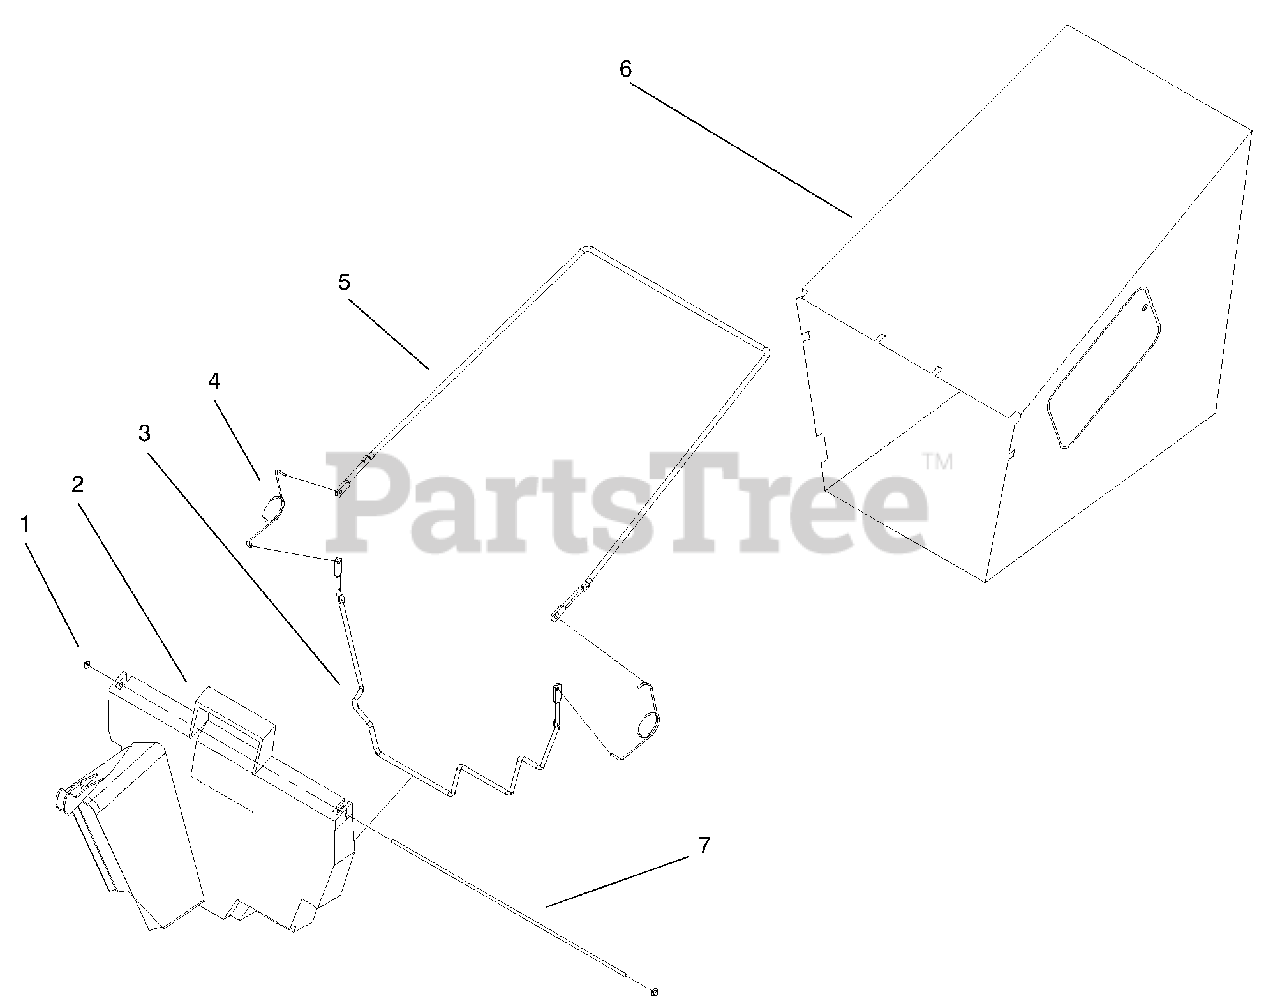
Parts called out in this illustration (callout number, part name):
2	Door-Bag
3	Frame-Lower Bag
5	Frame-Upper Bag
6	Bag-Grass
7	Hinge-Bag Door
